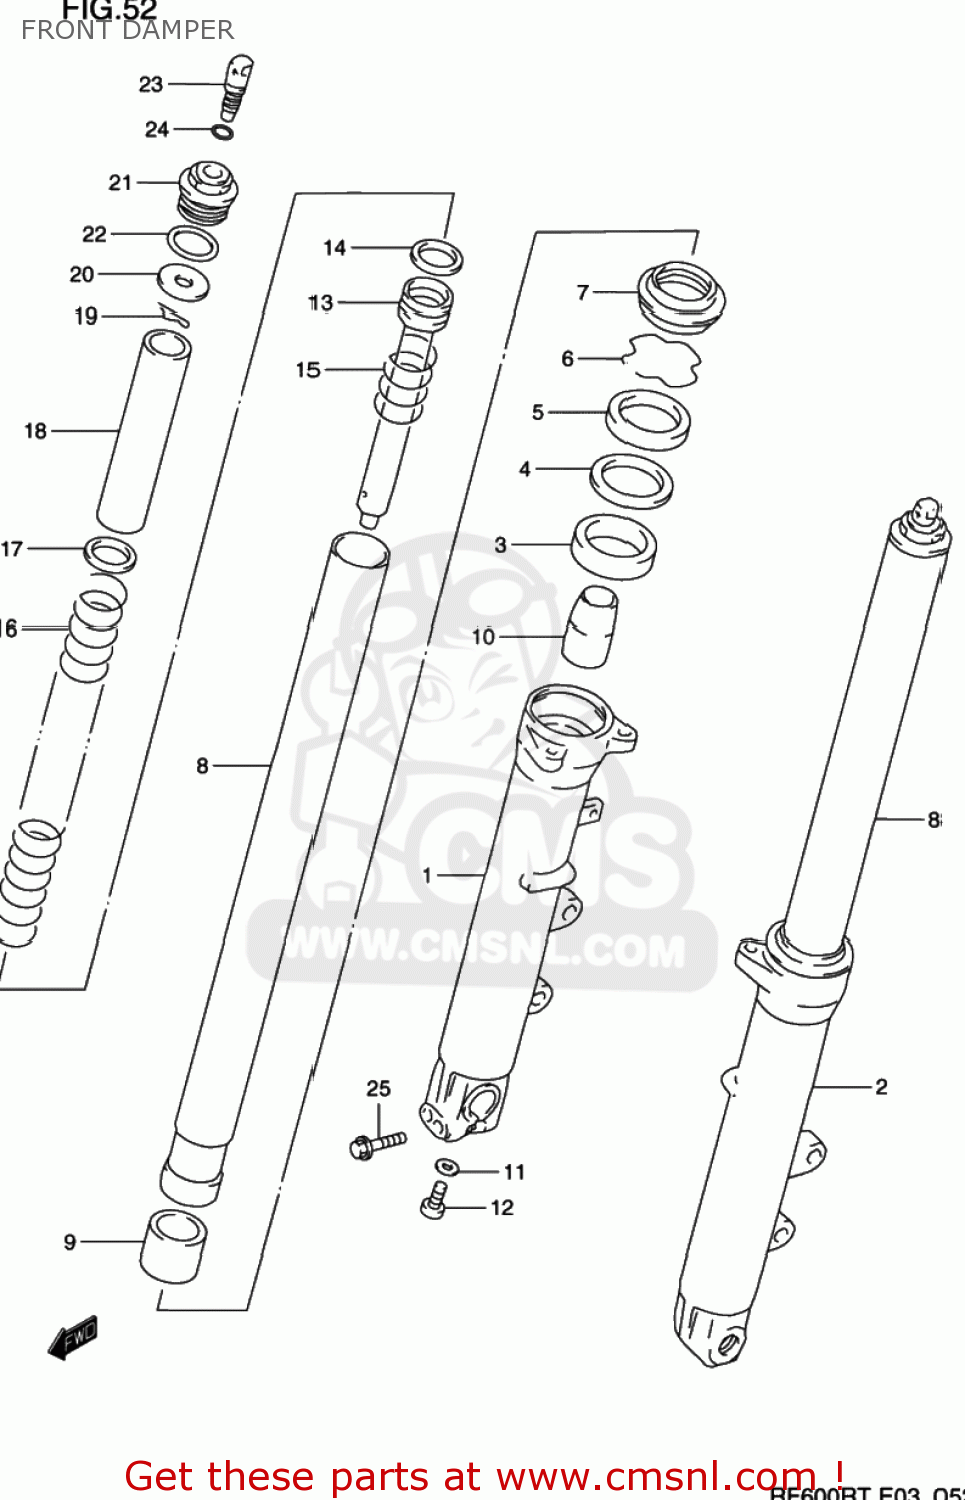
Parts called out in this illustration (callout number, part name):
1	TUBE,OUTER,RIGHT
2	TUBE,OUTER,L
3	BUSH,GUIDE
4	SPACER,SEAL
5	SEAL,OIL
6	CIRCLIP,FORK OIL SEAL
7	SEAL,DUST
8	TUBE,INNER
9	BUSH,SLIDE
10	PIECE,OIL LOCK
11	GASKET (NAS)
12	BOLT(8X27)
13	CYLINDER
14	RING,PISTON
15	SPRING,REBOUND
16	SPRING,MAIN
17	JOINT,SPRING
18	COLLAR,SPRING
19	PIN,SEAT SPRING
20	SEAT,SPRING
21	BOLT,FORK
22	O RING
23	BOLT,SPRING ADJUSTER
24	O RING(D:1.9,ID:8.6)
25	BOLT
